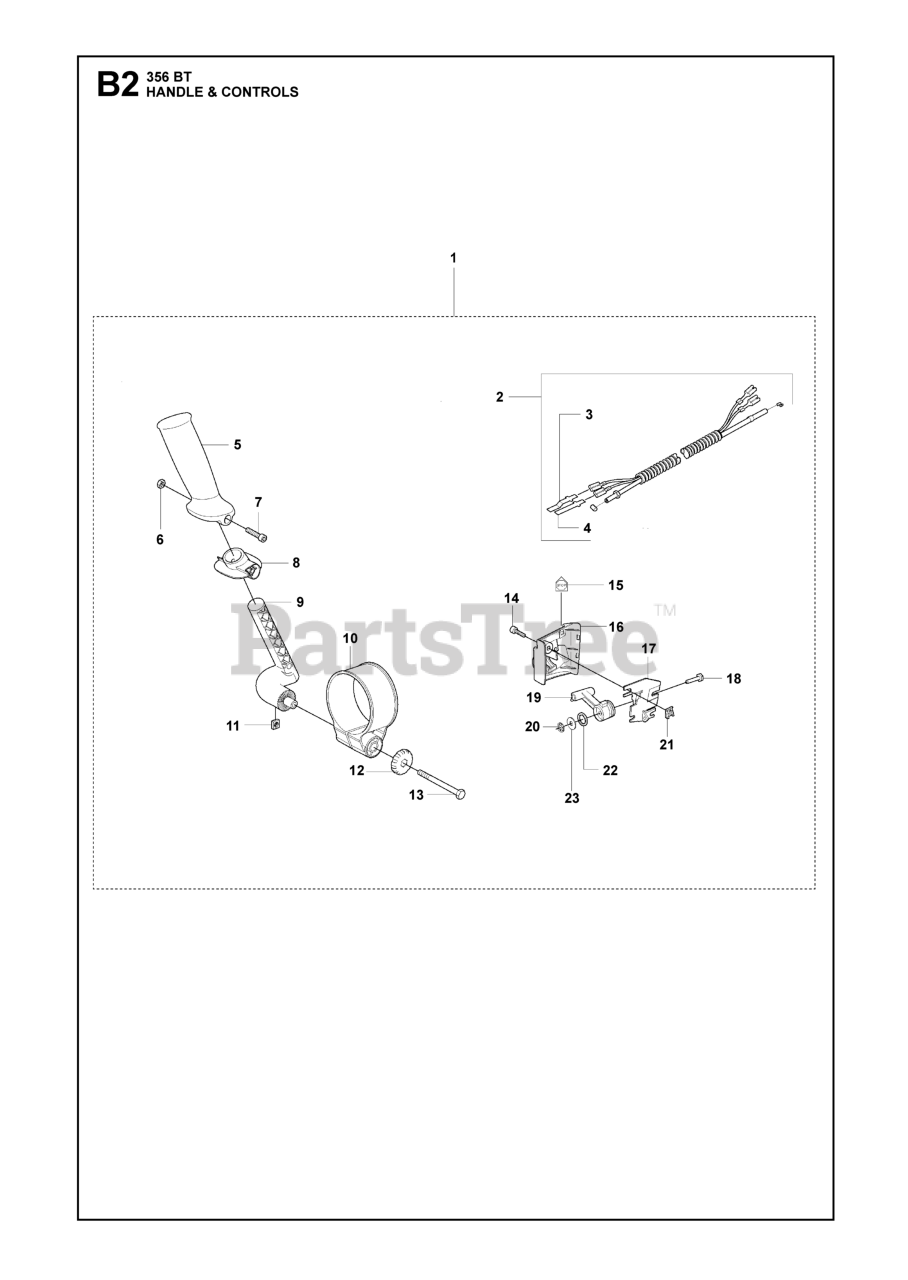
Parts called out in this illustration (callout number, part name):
2	CABLE ASSY
7	SCREW
9	BRACKET
22	SPRING RUBBER
